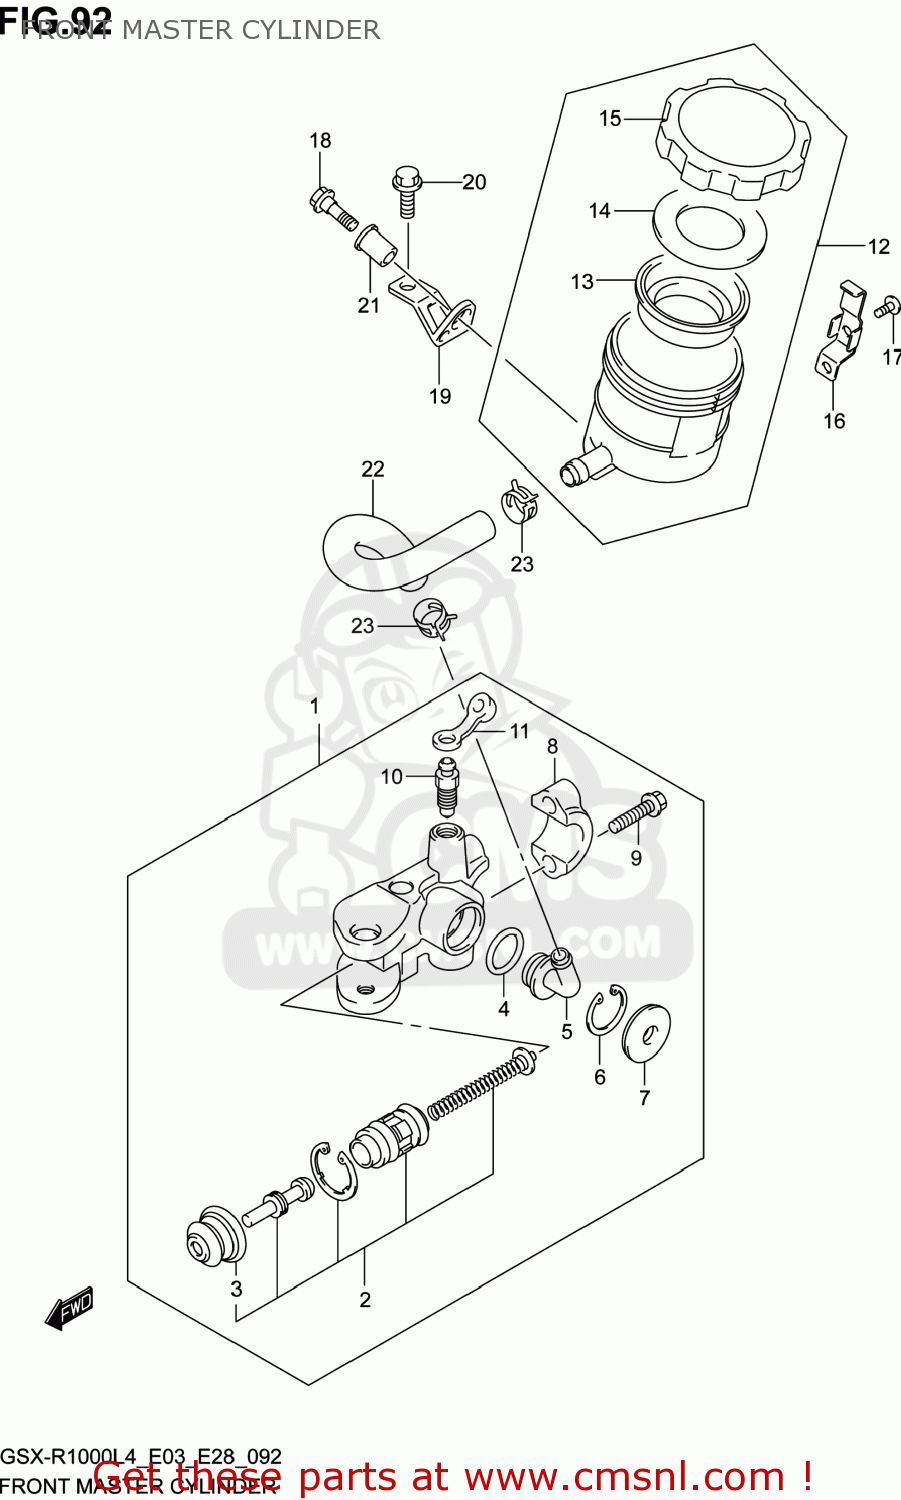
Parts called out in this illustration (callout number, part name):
1	CYLINDER ASSY,FRONT MASTER
2	PISTON & CUP S
3	BOOT
4	O RING
5	CONNECTOR
6	CIRCLIP
7	COVER,DUST
8	HOLDER
9	BOLT(6X22)
10	BLEEDER
11	CAP,BLEEDER
12	TANK ASSY,RESERVOIR
13	DIAPHRAGM
14	PLATE,DIAPHRAGM
15	CAP
16	PLATE,RESERVOIR TANK CAP
17	SCREW
18	BOLT(5X17)
19	BRACKET,FR RESERVOIR TANK
20	BOLT
21	NUT
22	HOSE,FRONT RESERVOIR TANK
23	CLAMP,RESERVOIR TANK FR
